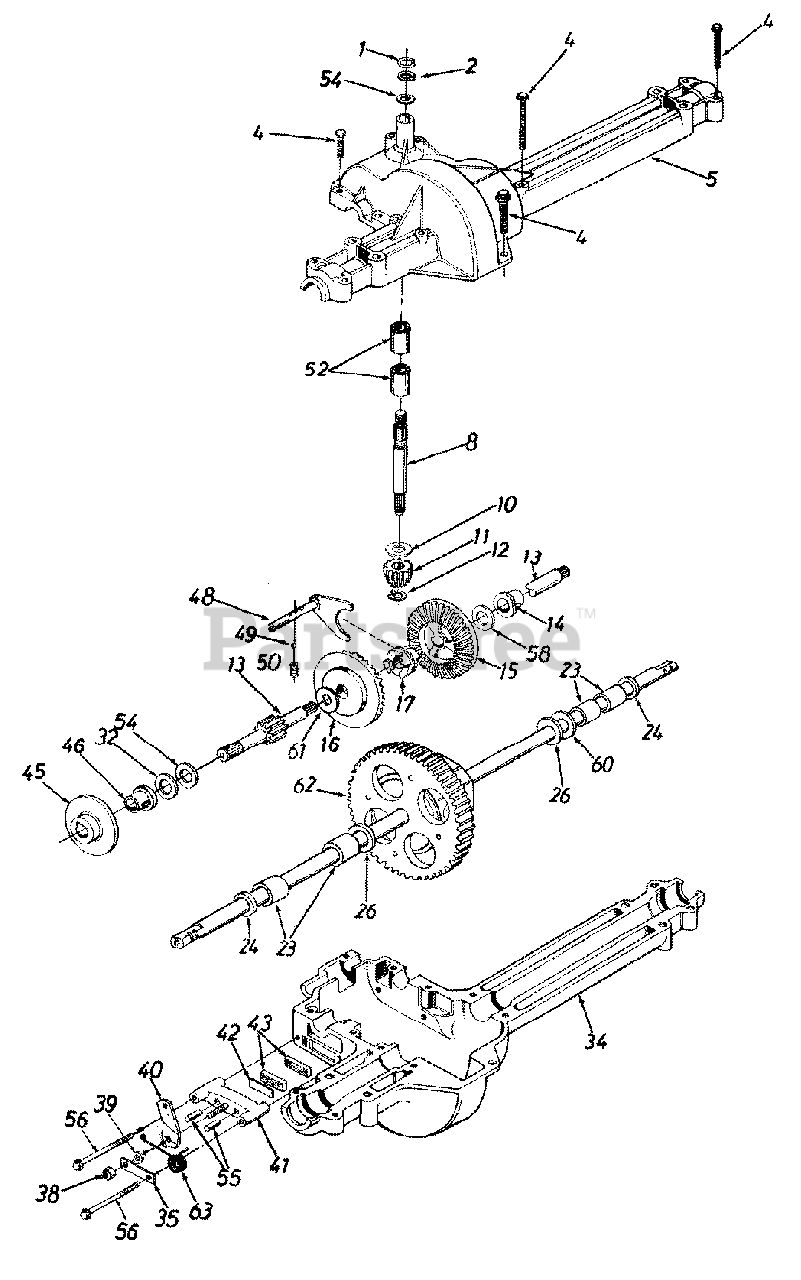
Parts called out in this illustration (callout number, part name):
2	Retaining Ring
4	Tap Scr. 1/4-20 x 1.625" Lg.
5	Upper Housing
10	Thrust Washer 5/8" I.D. x 1.25" Lg.
11	Pinion Input 14T
12	Retaining Ring
13	Drive Shaft L.H. Brake
14	Flange Brg. 5/8" I.D. x 3/4" Lg.
15	Bevel Gear 42T Small I.D.
16	Bevel Gear 42T Large I.D.
17	Clutch Collar
23	Sleeve Bearing 3/4" I.D. x 1.0"
24	Oil Seal 3/4" I.D.
26	Flat Washer .760" I.D. x 1.5" O.D.
32	Thrust Washer 5/8" x 1" x .025"
34	Lower Housing
35	Anti-Rotation Brkt.
38	Hex Nut 5/16-24 Thd.
39	Flat Washer .344" I.D. x .875" O.D.
40	Actuating Arm
41	Brake Yoke
42	Puck Plate
43	Brake Puck
46	Flange Bearing 5/8" I.D. x 15/16"
48	Shift Fork Ass'y.
49	Ball Detent .250" Dia.
50	Spring Detent
52	Needle Brg. 5/8" I.D. x 1/2" Lg.
54	Flat Washer 5/8" I.D. x 1" O.D.
55	Actuating Pin 5/16" Dia.
56	Hex Wash Hd. Self-Tap Scr.
58	Flat Washer 5/8" I.D. x 1" O.D. x
60	Flat Washer .76" x 1.5" x .010"
61	Thrust Washer
62	Differential Ass'y.
63	L.H. Brake Spring
